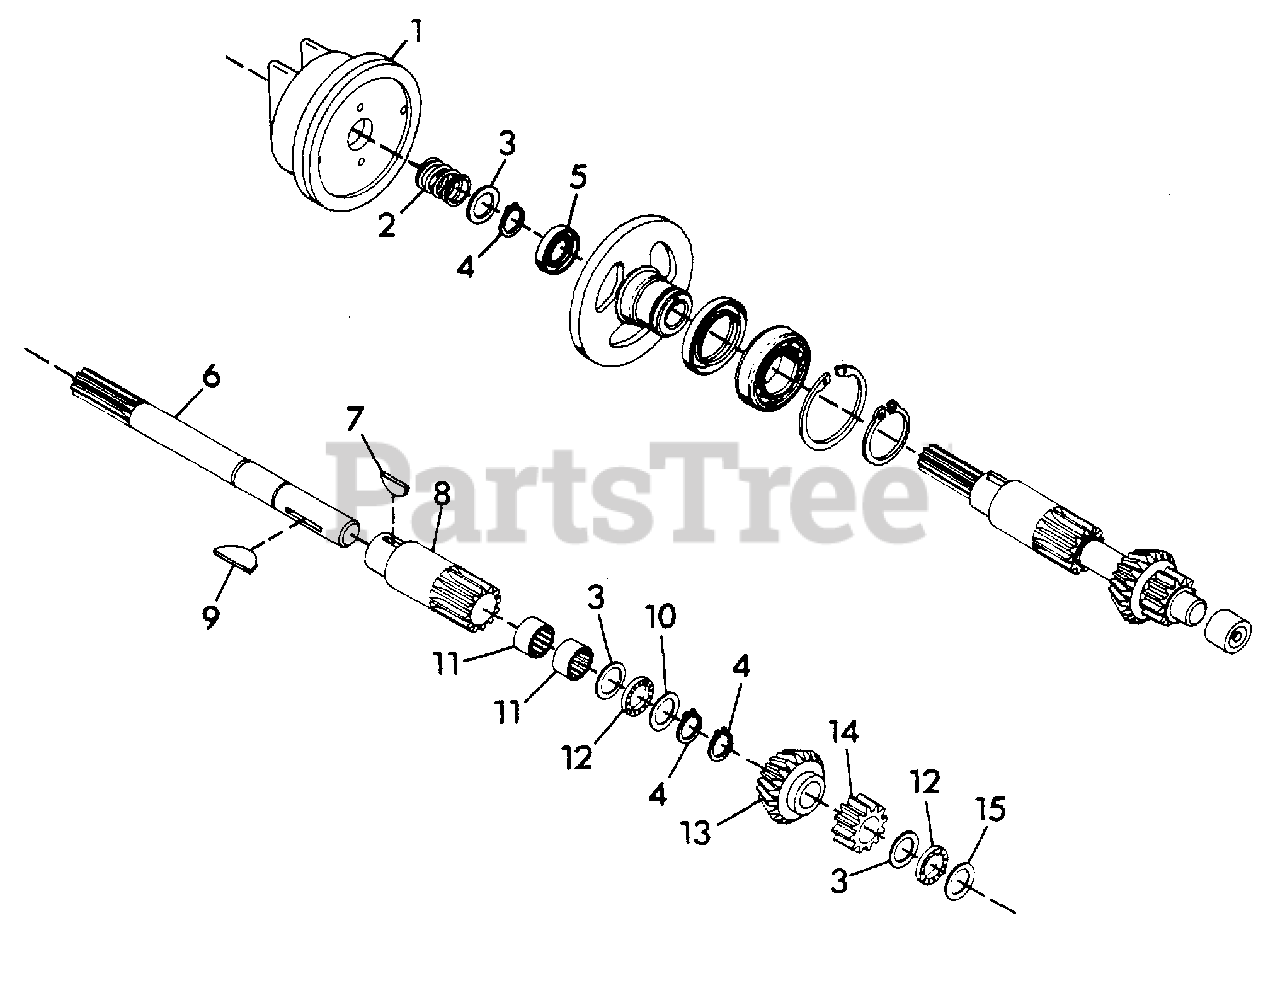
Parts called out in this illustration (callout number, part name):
1	NUMBER 11 - FWD-REV CLUTCH ASSEMBLY
2	SPRING, COMP. TYPE 1.0X.80X36 LB/IN
3	RACE, BEARING THRUST .752X1.240X.03
4	RING, RETAINING .750 SHAFT
5	SEAL, OIL .750X1.625X.250
6	SHAFT, SPLINED FORWARD CLUTCH
7	KEY, WOODRUFF .187X.625 HARD #61
8	GEAR
9	KEY, WOODRUFF .187X1.25 HARD #19
10	RACE, BEARING THRUST .060
11	BEARING, NEEDLE .75X1.00X.50
12	BEARING, NEEDLE THRUST
13	GEAR, BEVEL
14	GEAR, 10 DP 16 TEETH X .750
15	RACE, BEARING THRUST .095
